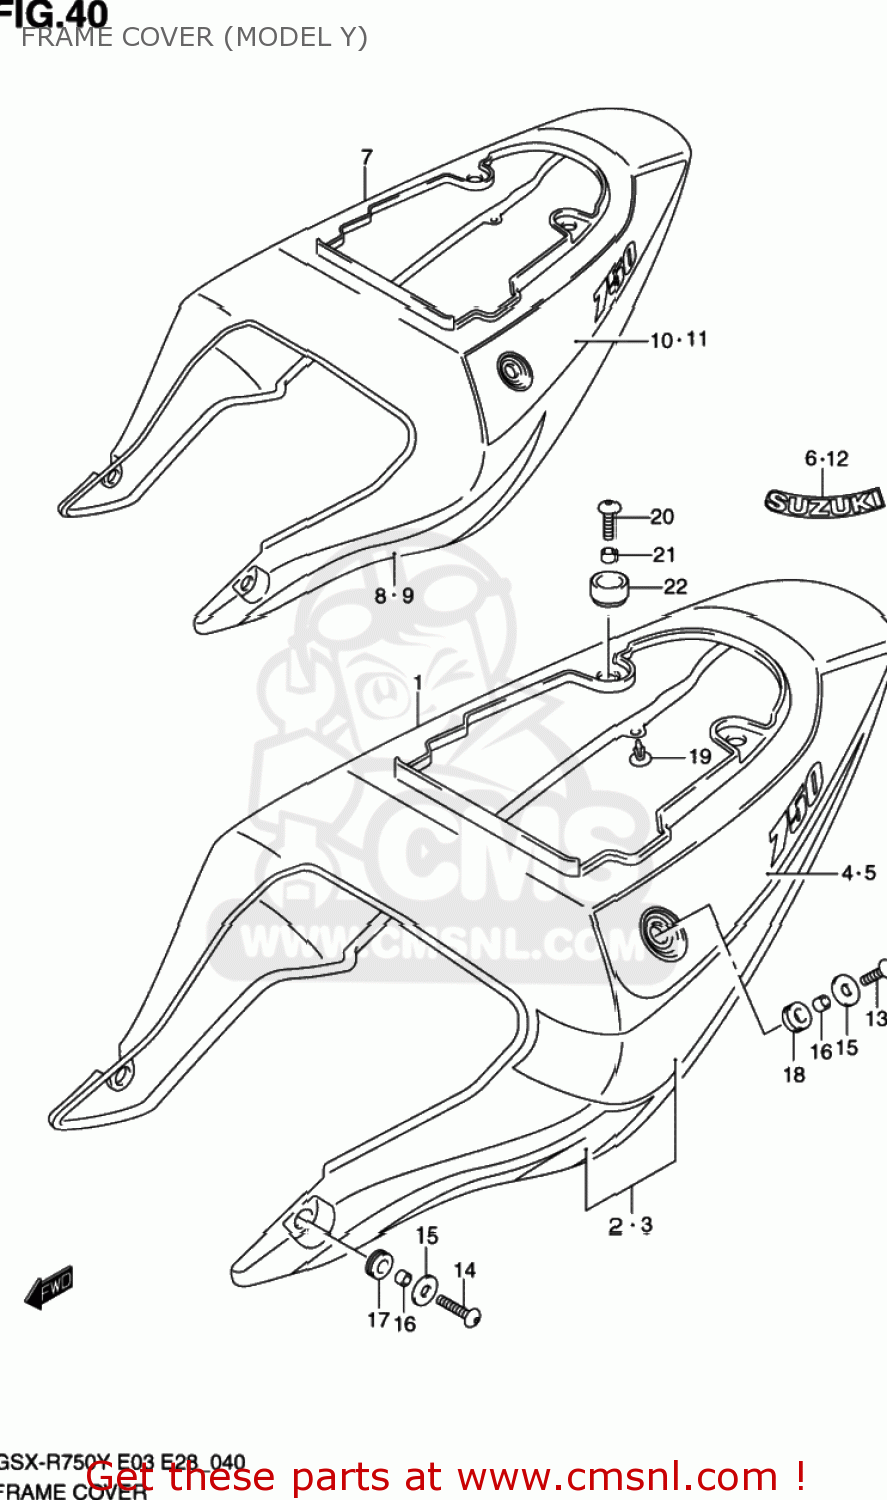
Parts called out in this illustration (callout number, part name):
1	COVER ASSY,FRAME(BLACK)
2	TAPE SET,FRAME COVER,R
3	TAPE SET,FRAME COVER,L
4	TAPE,FRAME COVER,R
5	TAPE,FRAME COVER,L
6	EMBLEM,SUZUKI
7	COVER ASSY,FRAME(BLACK)
8	TAPE,FRAME COVER,FRONT
9	TAPE,FRAME COVER FR,L
10	TAPE,FRAME COVER,R
11	TAPE,FRAME COVER,L
12	EMBLEM,SUZUKI
13	SCREW(6X25)
14	SCREW(6X30)
15	WASHER(6.5X20X2)
16	SPACER(6.5X10X7)
17	CUSHION,FRAME COVER FR
18	CUSHION,FRAME COVER SIDE
19	CLIP(BLACK)
20	SCREW(6X25)
21	SPACER(6.5X10X9.4)
22	CUSHION
